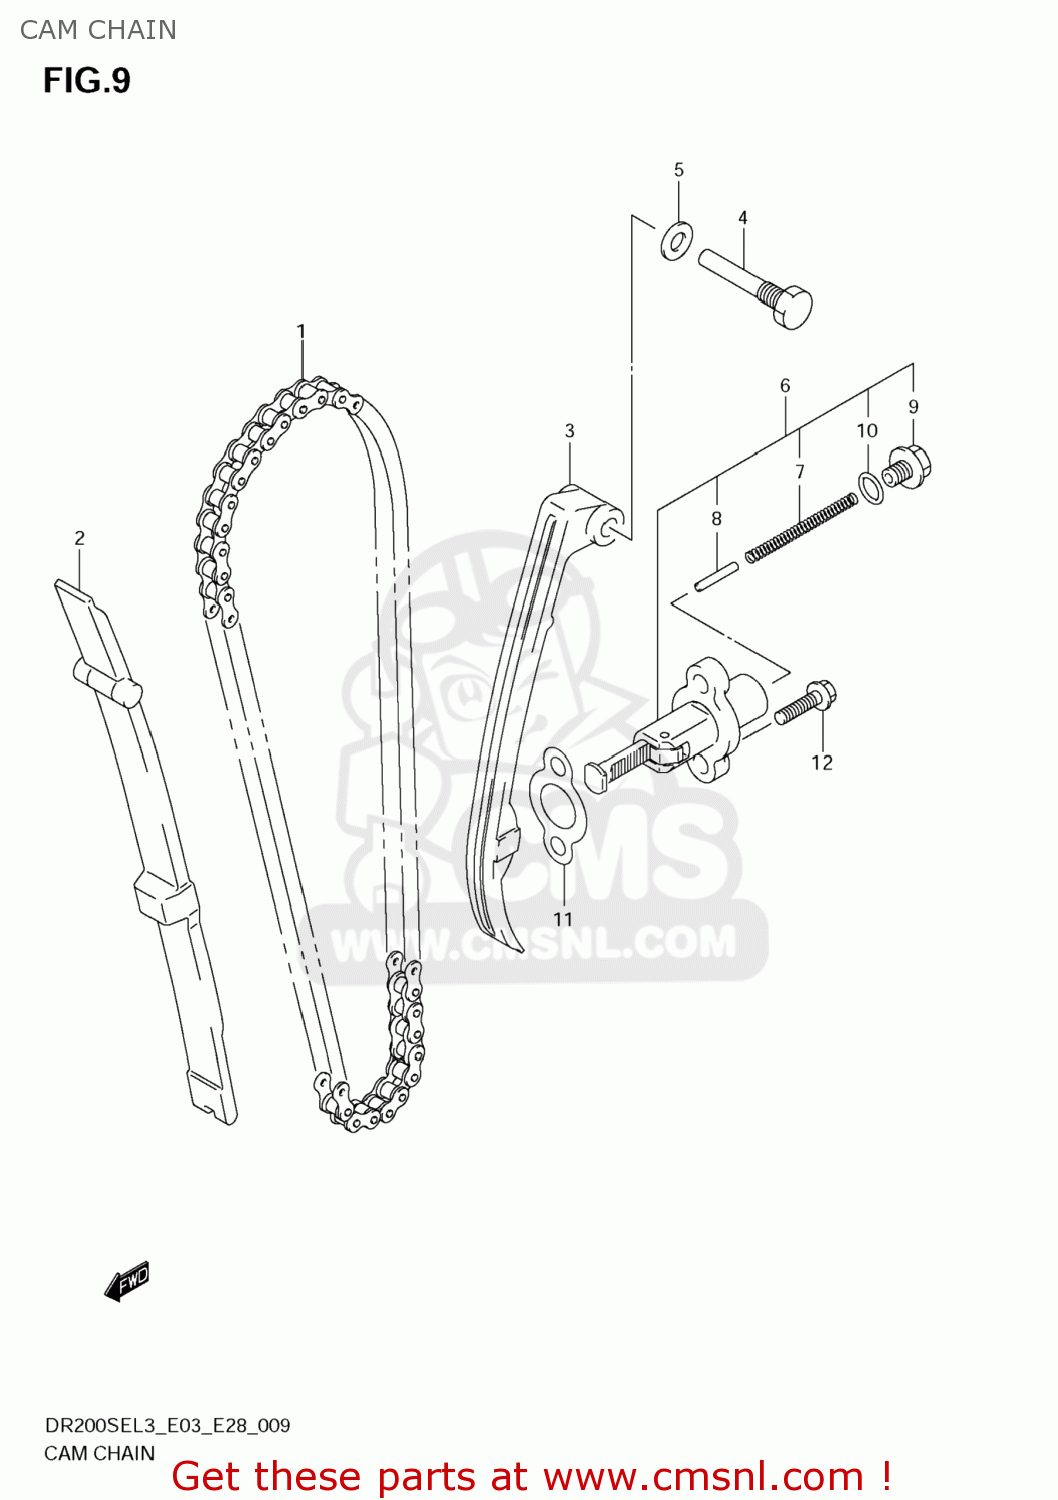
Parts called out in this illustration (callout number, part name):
1	CHAIN,CAMSHAFT DRIVE 102L
2	GUIDE,CAM CHAIN
3	TENSIONER,CAM CHAIN
4	BOLT,CAM CHAIN TENSIONER
5	GASKET(8.2X14X1) (NAS)
6	ADJUSTER ASSY,TENSIONER
7	SPRING
8	BAR
9	PLUG
10	O RING
11	GASKET,TENSIONER ADJUSTER (NAS)
12	BOLT
